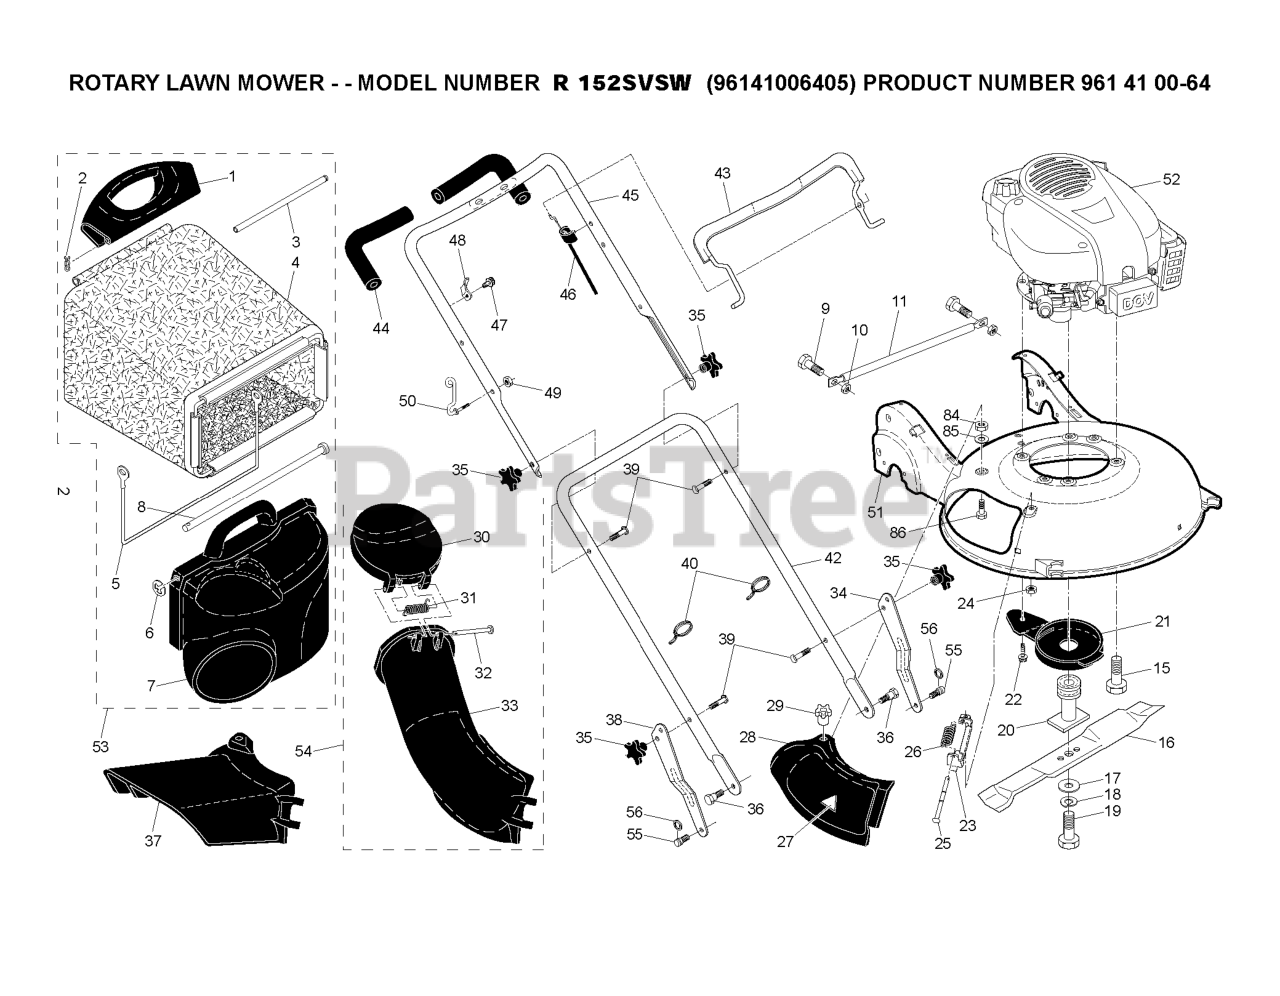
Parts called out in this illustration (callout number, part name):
1	HANDLE.GRASSBAG.REAR.H-GRAY
2	COTTER PIN (3 2)(2 2MC)
3	ROD.REAR.HANDLE.YELLOW
5	FRAME, GRASSBAG
7	DOOR, GRASSBAG
8	ROD, PIVOT
10	LOCKNUT.NYLOC.1/4-20
11	TUBE, REAR SKIRT
15	BOLT 3/8-16X1-1/8
16	Blade, 21"
17	WASHER,HARDEN
18	LOCKWASHER
19	BOLT.HD.HEAD.3/8-24X2.50 (2 2)
20	ADAPTER.BLADE
21	DEBRIS SHEILD
22	SCREW 1/4X20
23	BRACKET.ASM.HINGE
24	NUT.HEX.FLANGE.1/4
25	ROD.HINGE.1/4"3.82"
26	SPRING.MULCH.DOOR
27	DECAL.INTERNATIONL.CUTFINGER
28	MULCHER DOOR
29	KNOB.MULCH.DOOR
30	CHUTE.DOOR.21.HV.H-GRAY
32	ROD.HINGE.1/4"3.82"
33	DISCHARGE CHUTE PLASTIC
34	ADJUSTMENT BRACKET, LOWER LH
35	KNOB.HANDLE.PLASTIC.STAR.BLACK
36	SCREW.5/16X.680.TRIM.H
37	GUARD.CLIP.ON.21.HV.GRAY
38	BRACKET.ADJ.LOWER.HDL.RT.GREY
39	BOLT, HANDLE 5/16-18X1.75
40	TIE GUIDE
42	HANDLE.LOWER.GREY
43	BAIL.CONTROL.MZR.BS.ORANGE
44	GRIP.HANDLE.FOAM.WIDE.(1 SIDE)
45	HANDLE.ASM.UPPER.W/GRIP
46	CABLE.MZR.SNAP-IN
48	BRACKET.UPSTOP.RT
49	NUT
50	GUIDE.ROPE.WALK.MOWER
51	Kit, Housing
53	Grassbag Assembly, Complete
54	CHUTE.LOWER.ASM.WALK.MOWER
55	STUD.SHOULDER.T45.BZP
56	E-RING 7/16 RE
84	NUT, HEX
85	LOCKWASHER
86	BOLT.CARRIAGE.1/4-20 X 7/8
